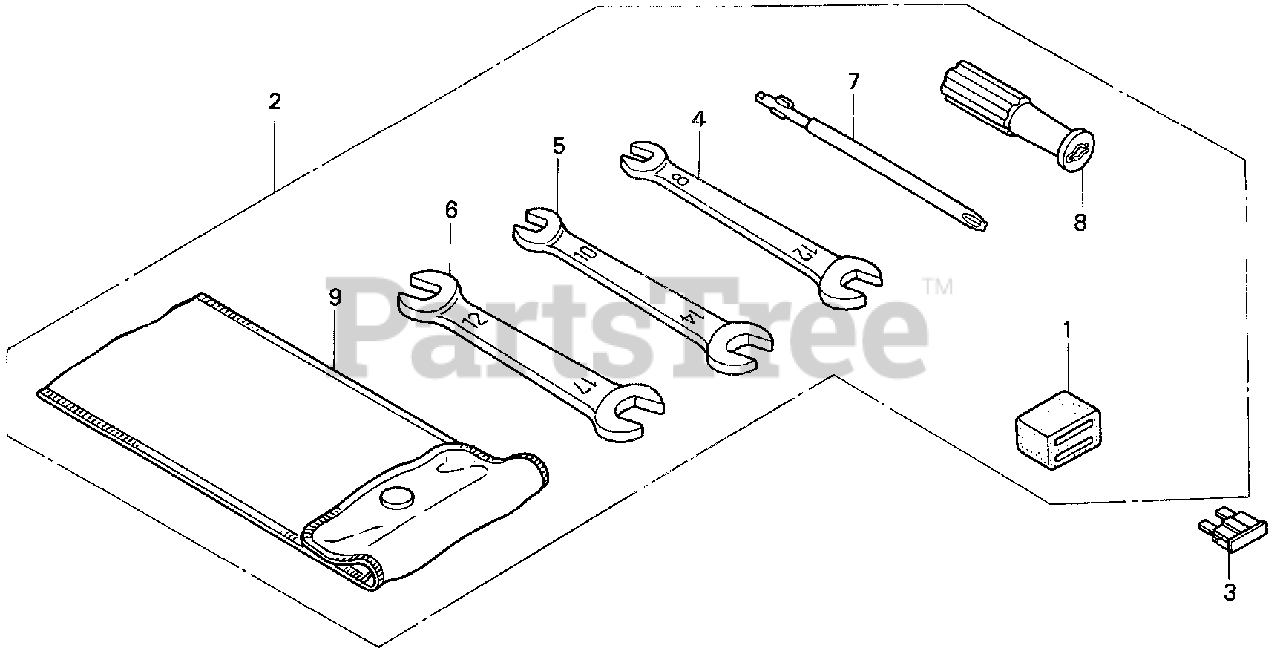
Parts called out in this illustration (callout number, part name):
1	SUSPENSION, TURN SIGNAL RELAY
2	TOOL KIT (NOT AVAILABLE)
3	FUSE, BLADE (5A)
4	WRENCH (8X12) (OPEN END)
5	WRENCH (10X14) (OPEN END)
6	WRENCH (12X17) (OPEN END) (NOT AVAILABLE)
7	SCREWDRIVER 2, PHILLIPS (NO.3)
8	GRIP
9	BAG, TOOL
